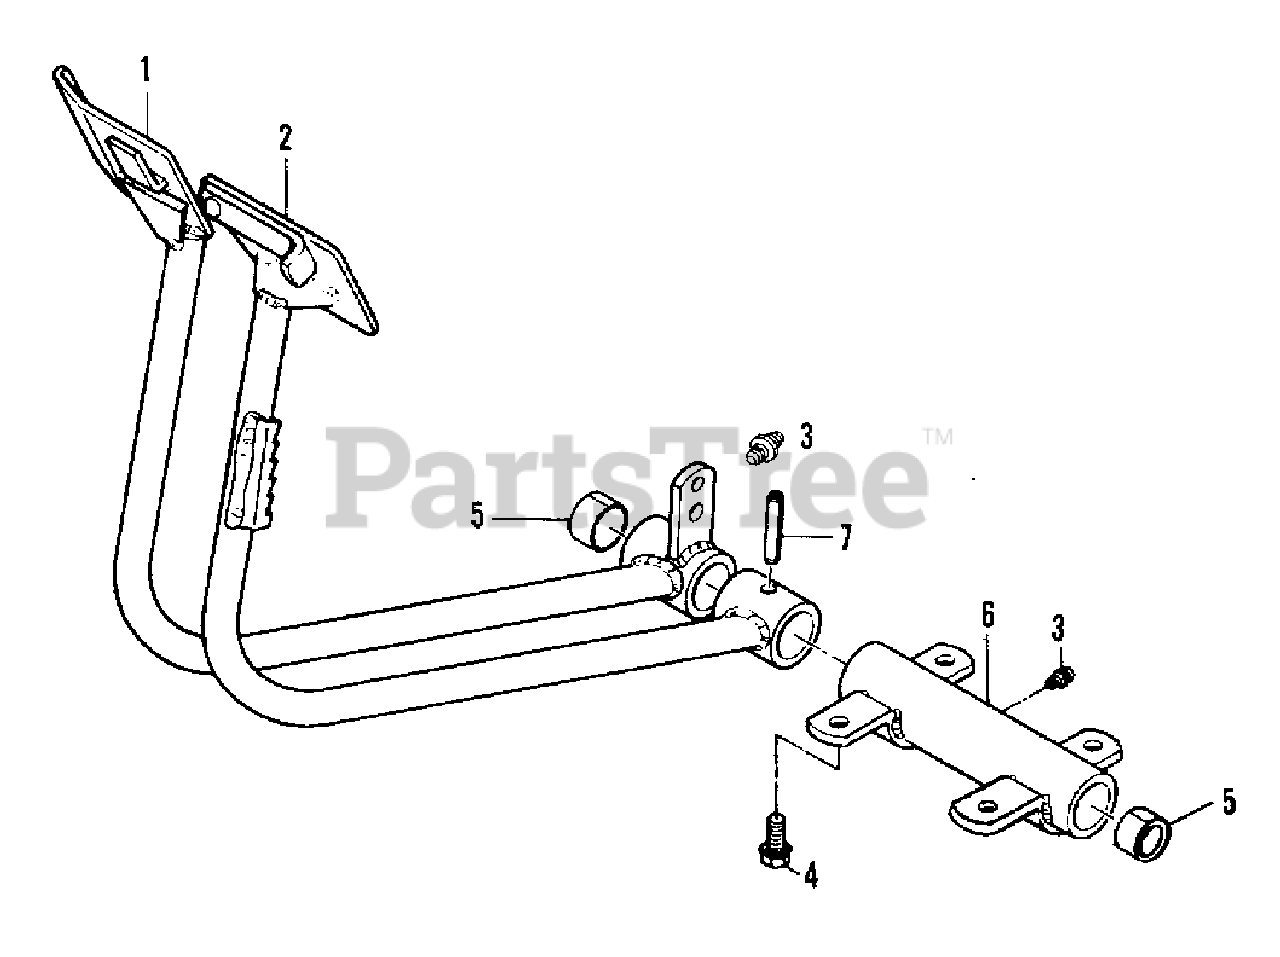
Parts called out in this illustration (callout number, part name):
1	PEDAL, right brake
2	PEDAL, left brake
3	FITTING, lube
4	CAPSCREW, M8 x 20
7	PIN, M8 x 40 roll
